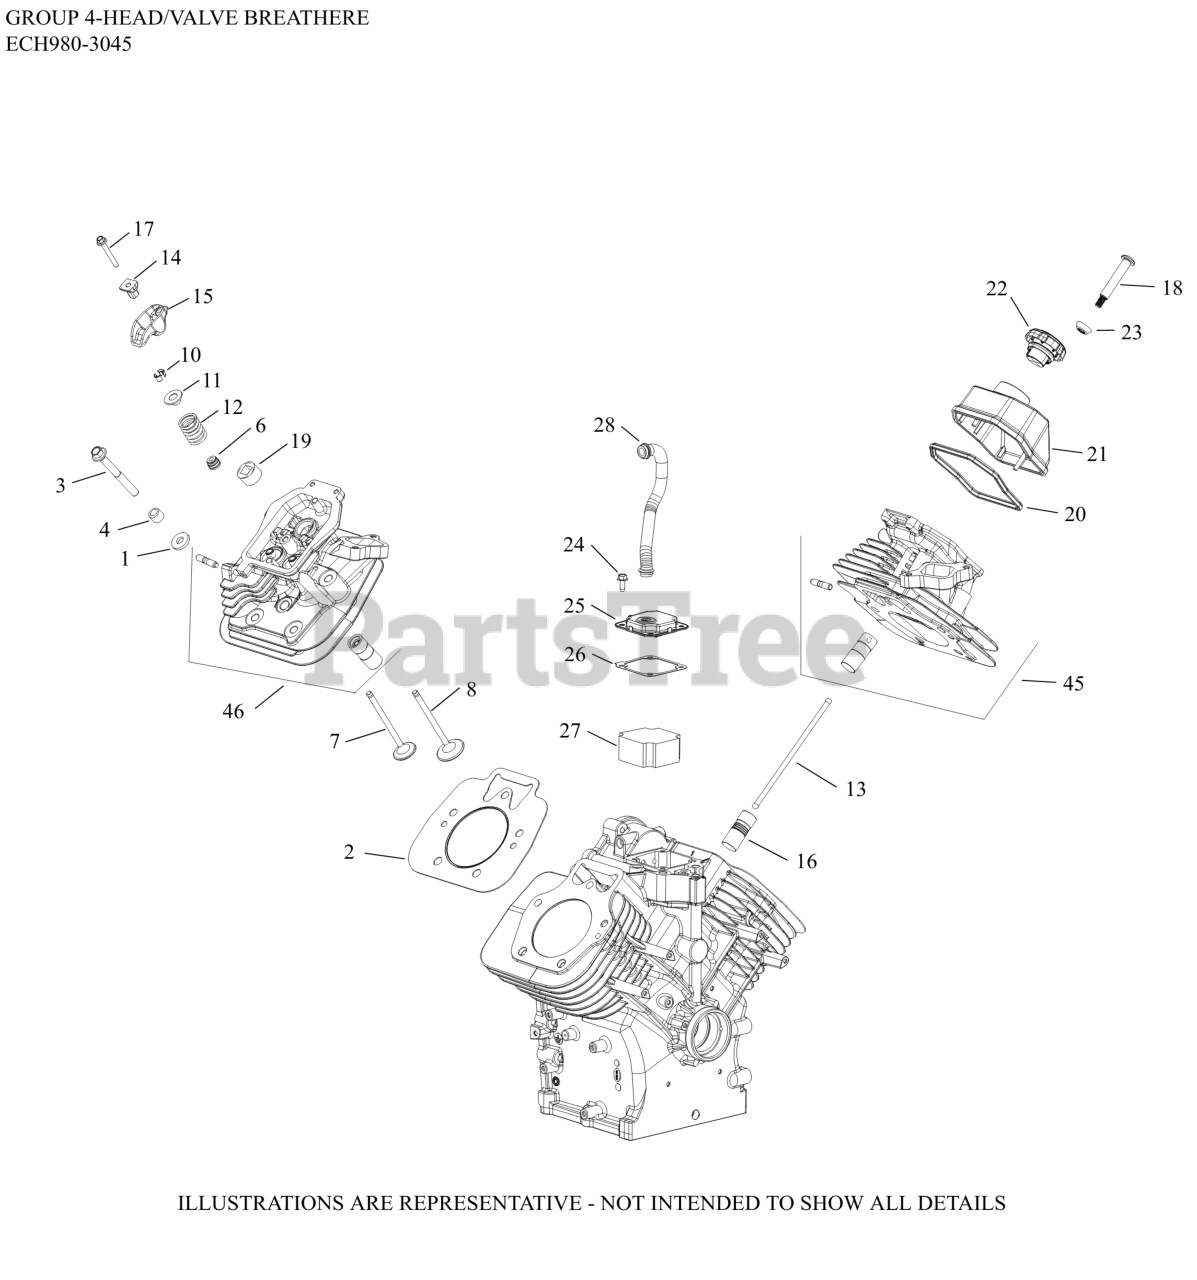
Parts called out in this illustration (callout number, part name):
1	WASHER, FLAT 13/32"
2	KIT, CYLINDER HEAD GASKET
3	SCREW, FLG M10X1.5X90
6	SEAL, VALVE BAND
7	VALVE, EXHAUST
8	VALVE, INTAKE
10	KIT, RETAINER
11	CAP, VALVE SPRING
12	SPRING, VALVE
13	ROD, PUSH
14	PIVOT, ROCKER ARM
15	ARM, ROCKER
16	LIFTER, VALVE HYDRAULIC-USE 25 351 11-S
17	SCREW,HEX FLANGE - USE 25 086 777-S
18	SCREW, SHOULDER
19	PLUG, PIPE 3/4 NPTF SQUARE
20	SEAL, PLASTIC VALVE COVER (BLACK)
21	KIT, COVER, VALVE (OIL FILL)
22	CAP ASSEMBLY
23	GROMMET, VALVE COVER SCREW
24	SCREW, THREAD FORMING
25	KIT, BREATHER ASSEMBLY
26	GASKET, BREATHER
27	FILTER, BREATHER-(#6205011S)
28	HOSE, BREATHER H/S
45	KIT, #1 CYLINDER HEAD COMPLETE
46	KIT, #2 CYLINDER HEAD COMPLETE
